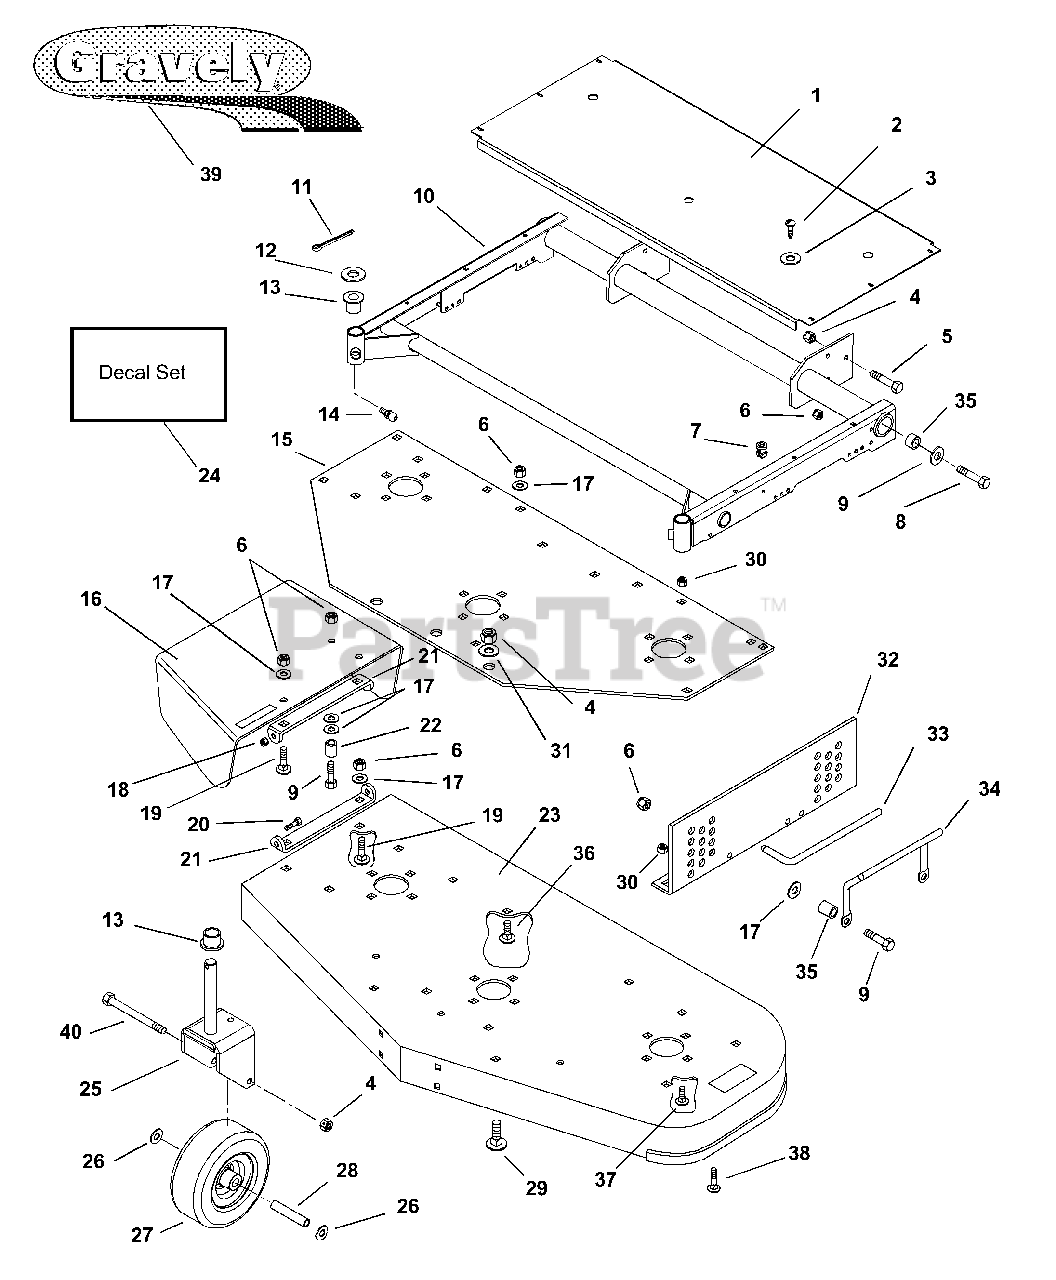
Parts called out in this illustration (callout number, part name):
1	Guard, 50"
2	Screw-Tapping, .25-20 x .50 Hex Slot Head
3	Washer-Flat-Steel .281 x .625 x .065
4	Nut, Locking .50-13
5	Bolt, Hex .50-13 x 1.50
6	Nut-Locking-Nylon .375-16 w/ Insr Grade 2
7	Grommet, Plastic
8	Bolt-Hex .38-16 x 1.50 Grade 5
9	Washer-Flat-Steel .390 x 1.5 x .125
10	Weldment, Mower Frame
11	Pin, Cotter .187 x 1.50
12	Race, Bearing Thrust
13	Bushing-Flange 1.03 x 1.75 x .750 Nylon
14	Fitting, Lube .25-28
15	Plate, Support
16	Shield, Safety Ext. 50" Mower
17	Washer-Flat-Steel .406 x .812 x .065
18	Nut, Locking .25-20
19	Bolt, Round Head Square Neck .375-16 x 1.00
20	Bolt, Hex .25-20 x .875
21	Bracket, Chute
22	Stop, Chute
23	Weldment, 50" Mower Fabricated
24	Decal, Set
25	Weldment, Caster Fork
26	Washer-Flat-Steel .812 x 1.496 x .134
27	Wheel, Gauge 9 x 3.50
28	Bearing, Gauge Wheel .750 x .532 x 3.97
29	Bolt, Round Head Square Neck .50-13 x 1.00
30	Nut, Locking .312-18 x .625
31	Washer-Flat-Steel 531 x 1.250 x .100
32	Bracket, Mower Side Support Left Hand
32	Bracket, Mower Side Support Right Hand
33	Pin, Mower Locking
34	Handle
35	Bushing
36	Bolt, Carriage .375-16 x .75
37	Bolt, Round Head Square Neck .312-18 x .625
38	Bolt, Carriage .312-18 x 1.00
39	Decal, Gravely Logo
40	Bolt, Hex .5-13 x 5.50
